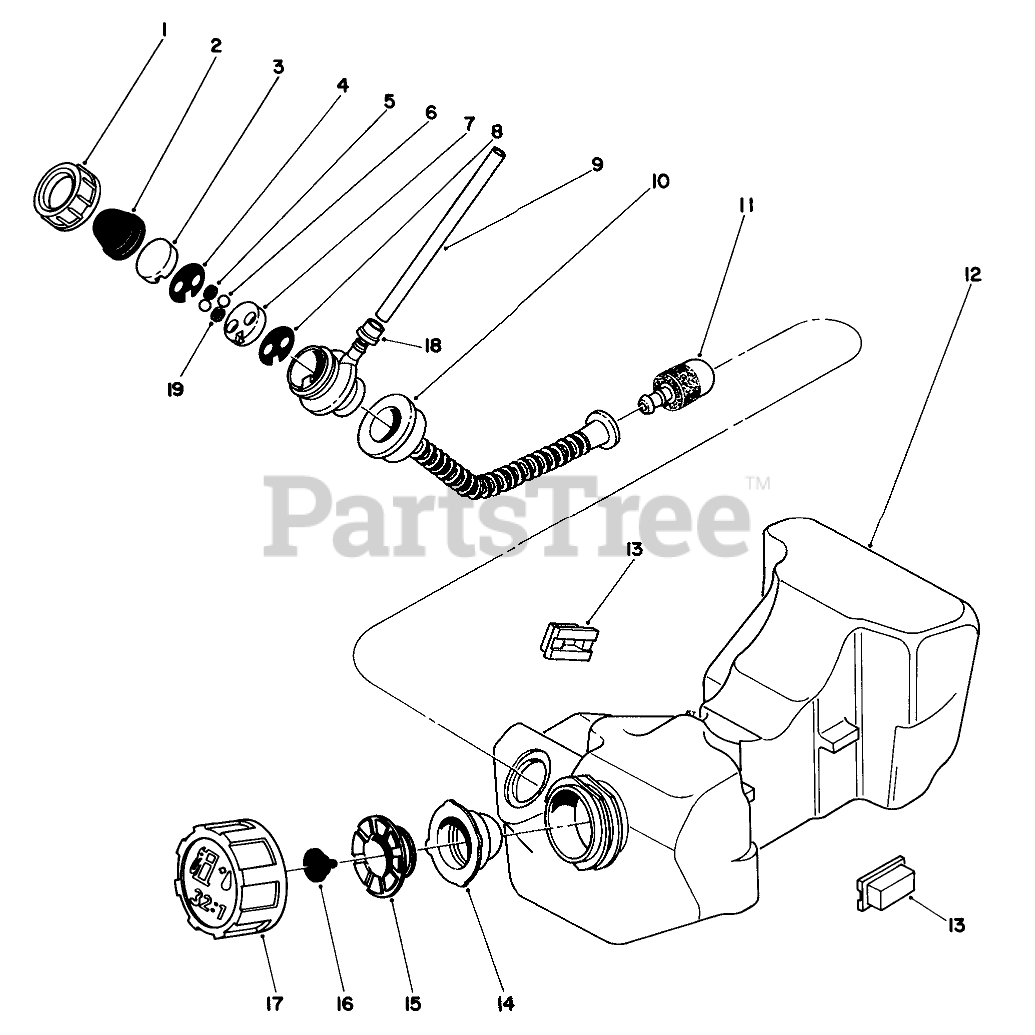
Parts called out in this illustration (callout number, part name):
1	PUMP CAP
3	SEAT VALVE
4	GASKET
5	SPONGE
7	SEAT VALVE
8	GASKET
9	Tube-Fuel
10	SUCTION HOSE
11	FUEL FILTER
12	Fuel Tank Assembly (Incl. Ref. #1-8, 10, 11, 14-17 & 19)
14	GASKET - PACKING
15	HOLDER
16	BREATHER VALVE
17	TANK CAP
19	Cushion Ball
